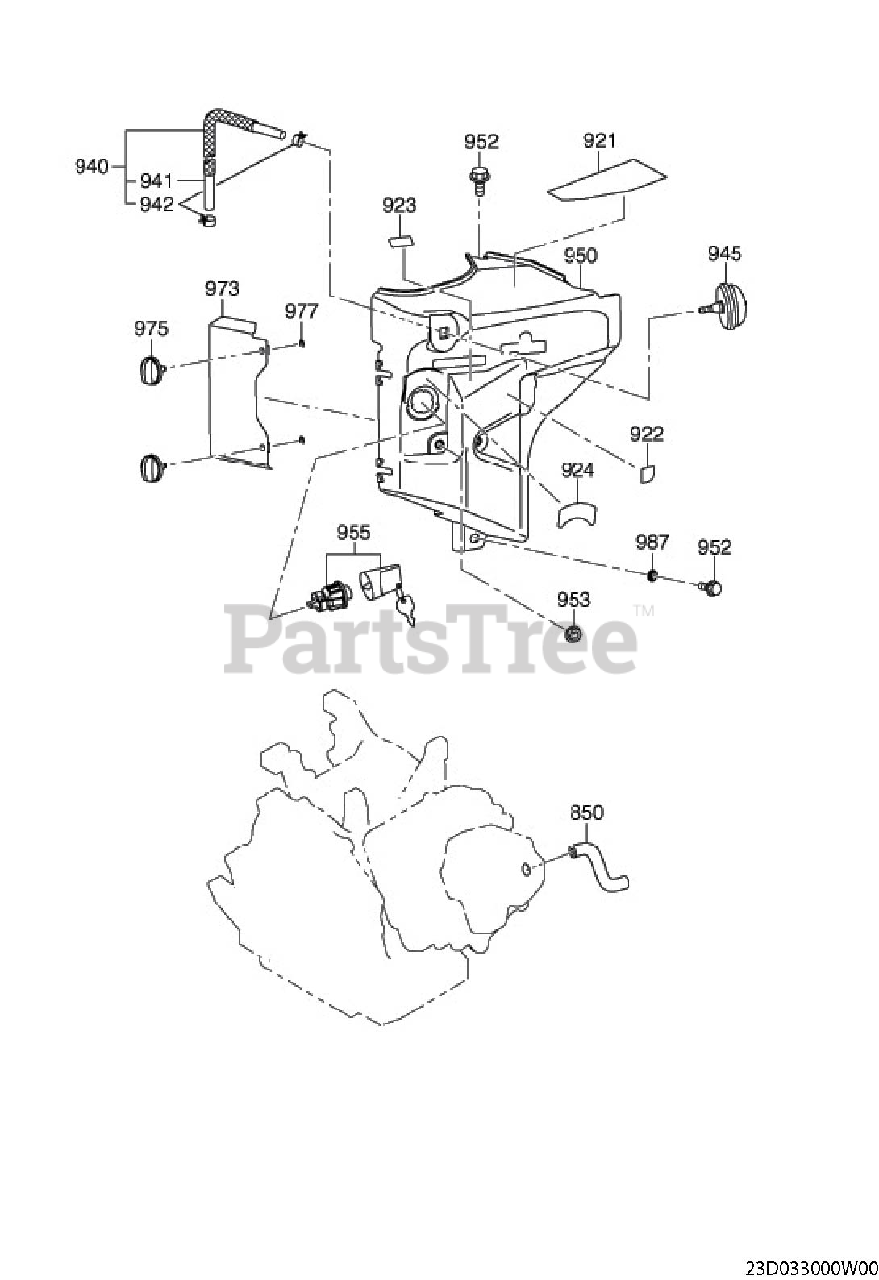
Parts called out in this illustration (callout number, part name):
850	RUBBER PIPE
921	LABEL(WARNING)
922	LABEL(F. COCK)
924	LABEL(KEY SWITCH)
940	PIPE CP
942	HOSE CLAMP
950	COVER(FRONT) UN
952	FLANGE BOLT
953	FLANGE NUT
955	SWITCH AY
973	BAFFLE 4 CP
975	KNOB BOLT
977	CLIP
987	SPACER
